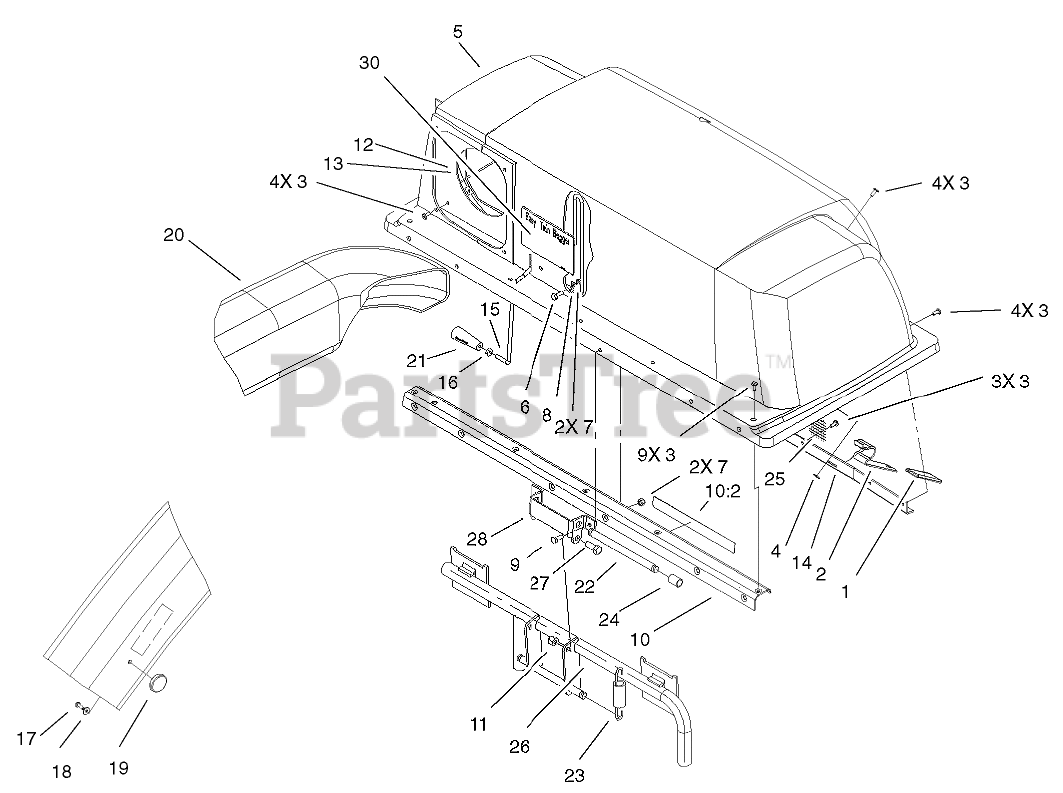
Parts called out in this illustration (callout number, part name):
2	LATCH-BAGGER, TOP
3	RIVET-BLIND
4	WASHER-FLAT
5	TOP-BAGGER
6	SCREW-HH
7	NUT-LOCK, NI
8	CLAMP
9	SCREW-HH
10	BAG STIFFENER ASM
10:2	DECAL-CAUTION
11	NUT-LOCK, NI
12	CLAMP-SEAL
13	SEAL-CHUTE
14	SUPPORT-SCREEN
15	FEELER-FILL, BAG
16	NUT-JAM
17	SCREW-PPHTF
18	WASHER-PLAIN
20	Chute-Discharge
21	HANDLE-TAPERED
22	PIN-SPRING
23	SPRING-EXTENSION
24	Spacer
25	SCREEN-BAGGER
26	FRAME ASM
27	SCREW-HH
28	Hinge-Bag, Top
30	DECAL
